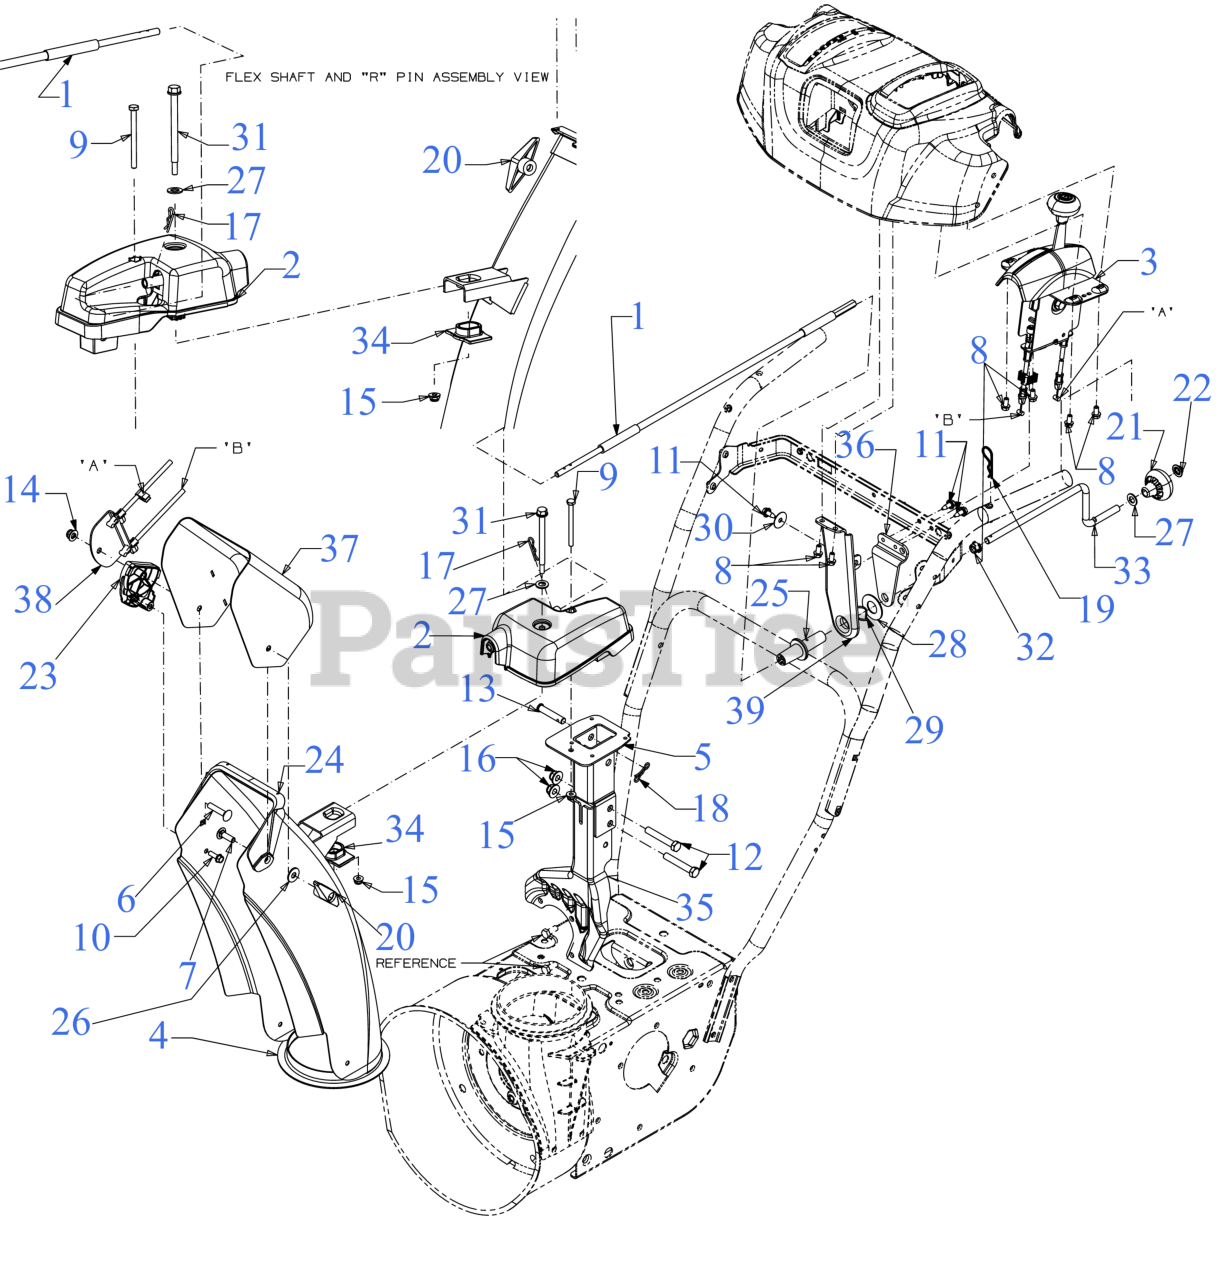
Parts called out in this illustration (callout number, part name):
1	CHUTE CONTROL
2	2-WAY CHUTE ROTATE GEARBOX
3	CHUTE CONTROL ASSEMBLY-2-WAY
5	EXTENSION CHUTE MAST
6	CARRIAGE BOLT 5/16-18 x 1.50
7	CARRIAGE BOLT 5/16-18 x 1.00
8	HEX SCREW 1/4-15 x .50
9	SCREW 1/4-20 x 3.0 GR5
10	SCREW 1/4-15 x .750
11	SCREW 1/4-20X.625
12	SCREW 3/8-16 x 2.25 GR5
13	CLEVIS PIN 3/8 x 1.87
14	FLANGE LOCK NUT 5/16-18
15	FLANGE LOCK NUT
17	INTERNAL COTTER PIN
18	BOW TIE COTTER PIN 1/4-5/16
19	INTERNAL COTTER PIN
20	WING KNOB NUT
21	SHIFT KNOB
23	CHUTE TILT GUIDE
24	UPPER CHUTE ADAPTER
25	CHUTE ROD COUPLER
26	FLAT WASHER
27	FLAT WASHER
28	FLAT WASHER
29	WAVE WASHER .785X1.00X.012
30	FLAT WASHER
31	SHOULDER SCREW
32	BUSHING .380 ID
33	CHUTE CRANK (POWDER BLACK)
34	HELICAL GEAR CHUTE ADAPTER
36	ROD SUPPORT BRACKET
